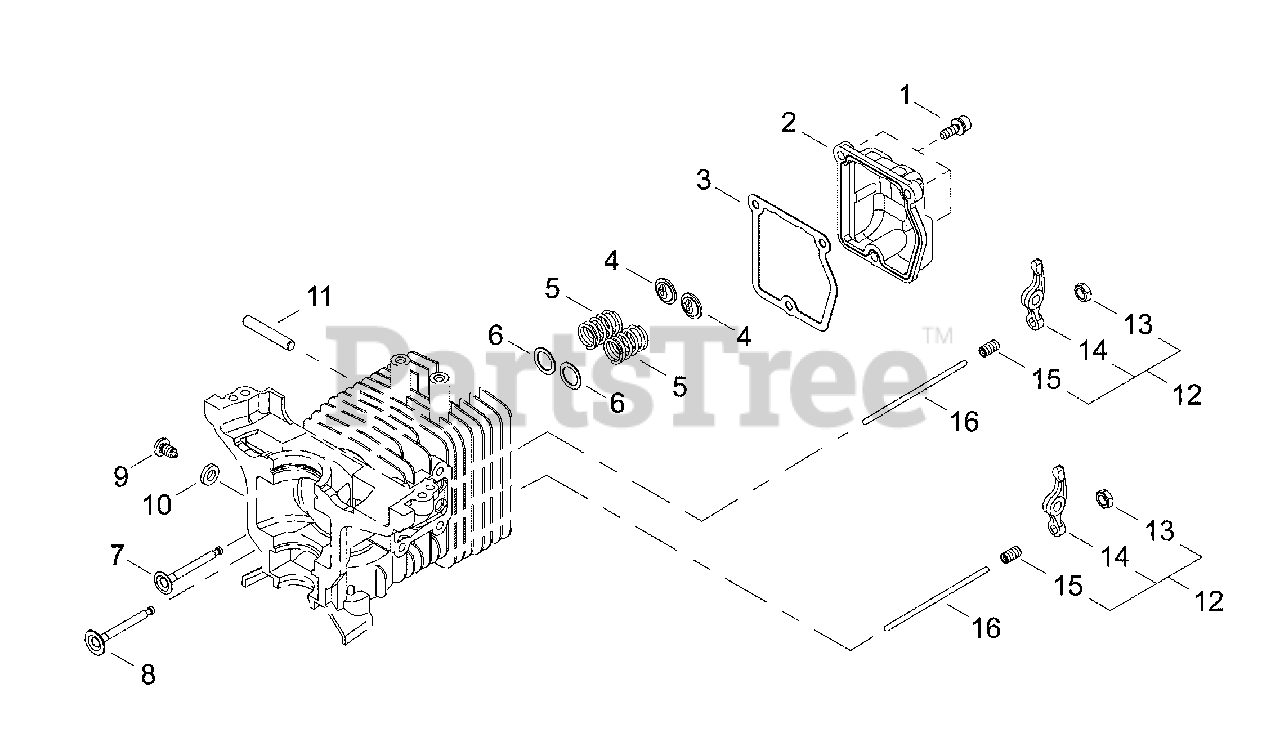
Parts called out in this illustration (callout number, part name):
1	BOLT M4×12
2	COVER, ROCKER ARM
3	GASKET, ROCKER ARM
4	RETAINER, VALVE
5	SPRING, VALVE
6	WASHER, VALVE 9
7	VALVE, EXHAUST
8	VALVE, INTAKE
9	SCREW M5
10	WASHER Ø10ר5.5×2
11	SHAFT, ROCKER ARM Ø5×31.8 MM
12	ARM ASSY, ROCKER
13	NUT, ADJUSTER LOCK 5
14	ARM, ROCKER
15	SCREW, ADJUSTER
16	PUSHROD
